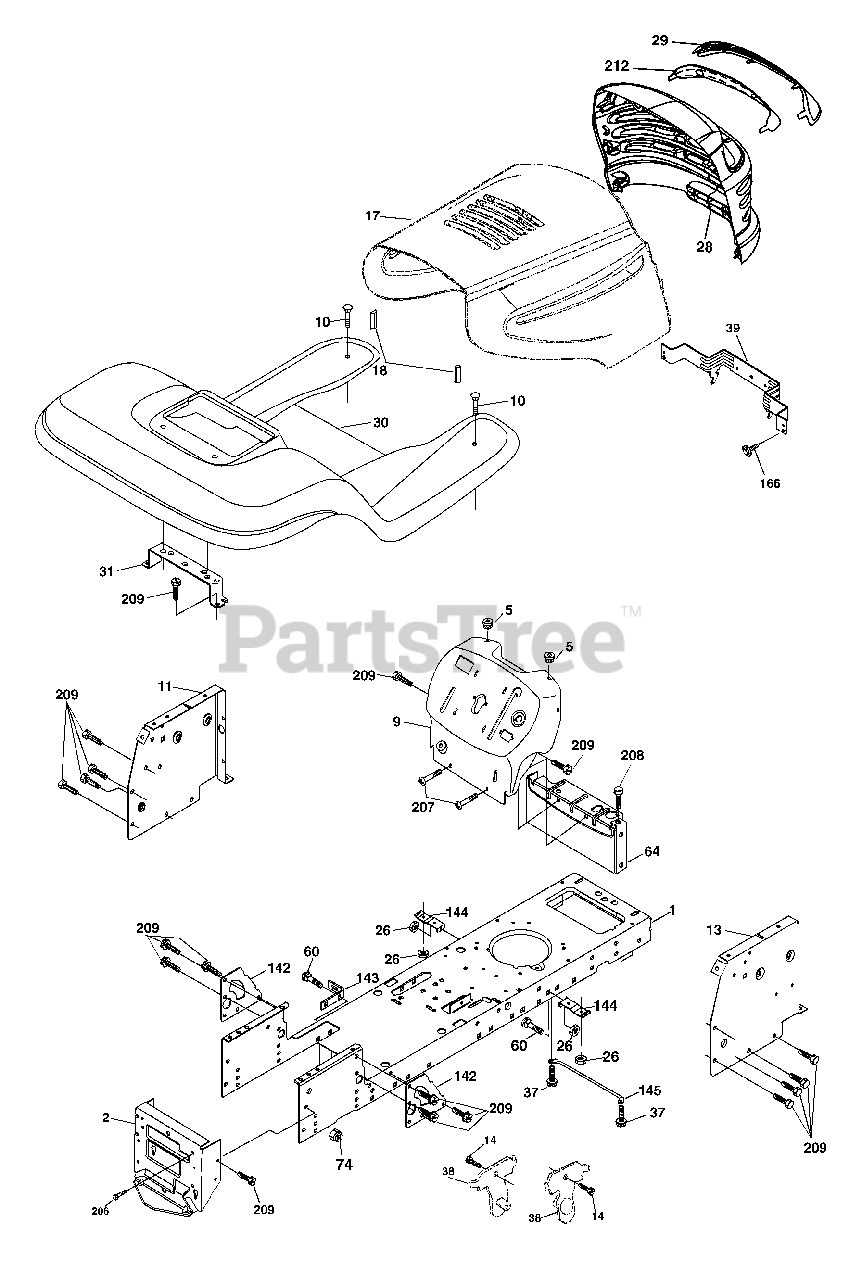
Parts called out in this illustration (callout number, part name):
1	Chassis
2	Drawbar
5	Bumper Hood/Dash
10	Bolt, Carriage 3/8-16 x 3/4
11	Panel, Dash, L.H.
13	Panel, Dash, R.H.
14	Screw Thdrol 3/8-16 x 1/2
17	Hood
18	Bumper Hood
26	Nut
28	Grille/Lens Asm.
29	Lens Grille
31	Bracket, Fender Support
37	Screw Thdrol 5/16-18 x 1/2
38	Pivot Bracket Assembly, Rear
39	Bracket Pivot Laser Lt
60	Bolt Rdhd Sqnk 3/8-16 UNC x 1
64	Dash Lower STLT
74	Nut Crownlock 3/8-16 UNC
142	Plate Reinforcement STLT
143	Bracket Swaybar Chassis
144	Bracket Pnt Footrest STLT
145	Rod Pivot Chassis/Hood
166	Screw 10 x 3/4 Single Lead-Hex
206	Bolt Shoulder 5/16-18 TT
207	Screw Thdrol 5/16-18 x 1/2 Tytt
208	Screw Thdrol 3/8-16 x 1/2
209	Screw Hexwsh Thdr. 3/8-16 x 3/4
212	Insert Lens Reflective
